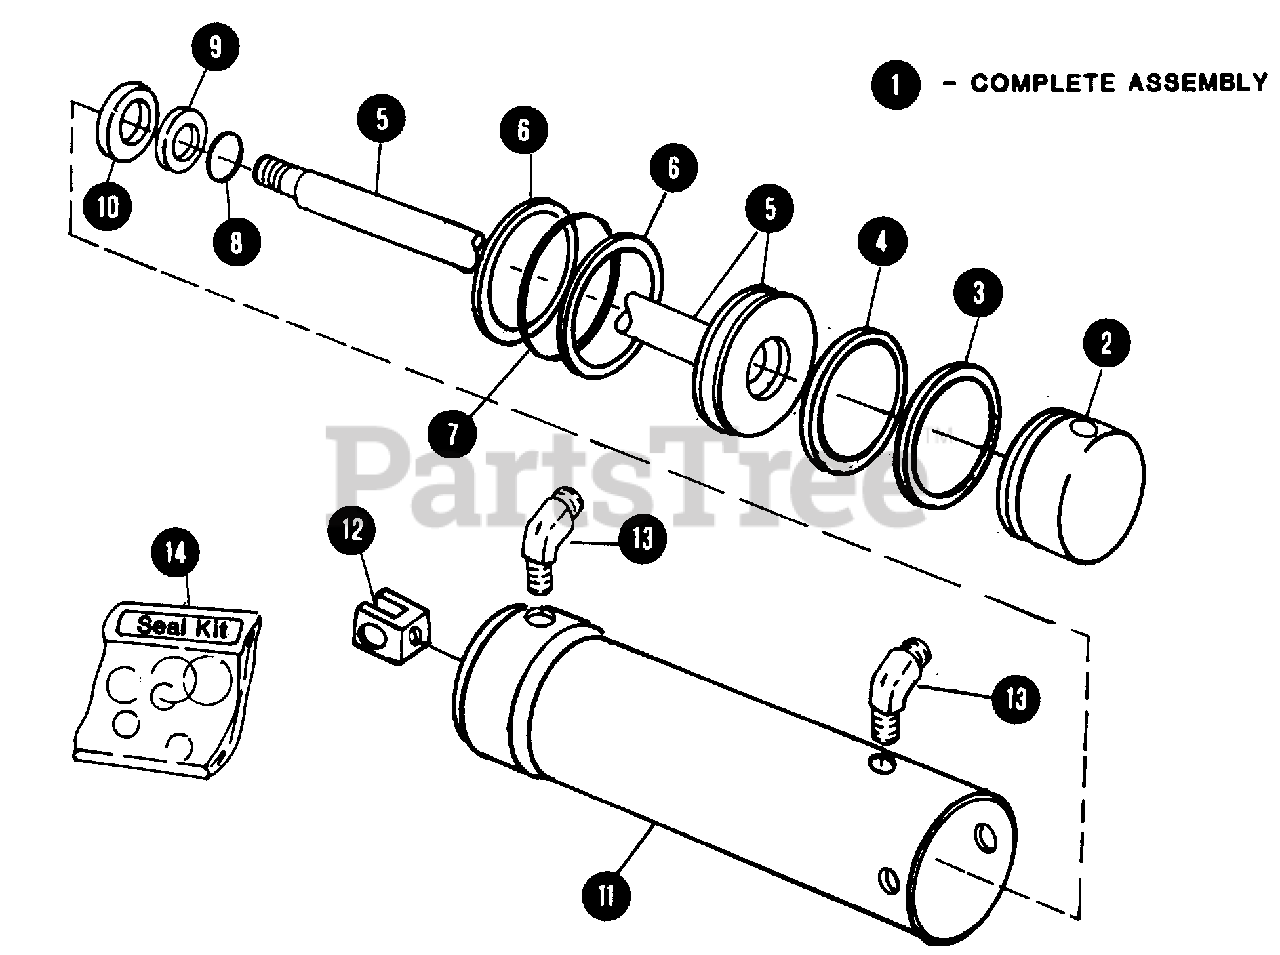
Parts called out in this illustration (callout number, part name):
1	CYLINDER, REAR LIFT ASSEMBLY
2	HEAD, CYLINDER
3	WASHER, HEAD O-RING BACK-UP
4	O-RING, CYLINDER HEAD
5	PISTON-ROD ASSEMBLY
6	WASHER, PISTON O-RING BACK-UP
7	O-RING, PISTON
8	O-RING, PISTON ROD SEAL
9	WASHER SEAL O-RING BACK-UP
10	WIPER, PISTON ROD
11	TUBE CYLINDER
12	FITTING, PISTON ROD END
13	ELBOW, 1/4 P.T. - 45°.
14	KIT, SEAL REPLACEMENT
